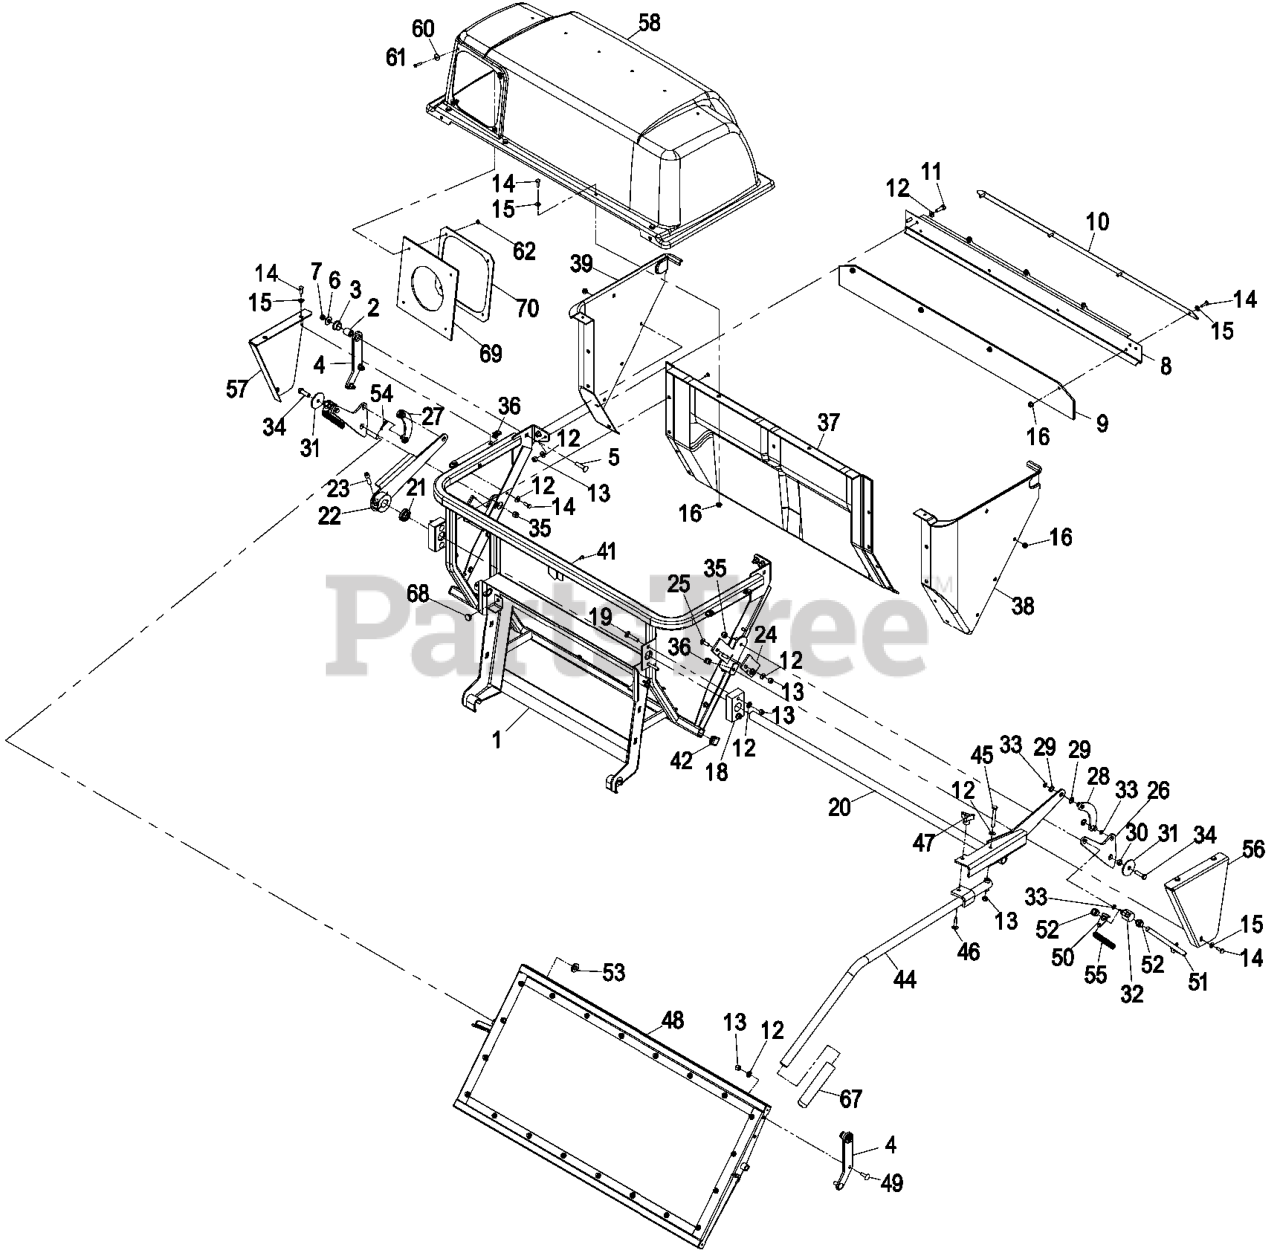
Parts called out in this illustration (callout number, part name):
1	FRAME ASM
2	PIN-PIVOT, HINGE
3	BEARING
4	PLATE-HINGE
5	SCREW-CARR
6	WASHER-FLAT
8	PLATE-REAR
9	SEAL-DOOR
10	STRAP-HOLD DOWN
11	SCREW-HH
12	WASHER-PLAIN
13	NUT-LOCK, NI
14	SCREW-HH
15	WASHER-FLAT
18	BEARING
19	BOLT-CAR
20	BELLCRANK
21	SHAFT-COLLAR
23	SCREW-HSH
24	STOP-LINKAGE
25	BOLT-CARR
26	ARM-LINKAGE, DOOR
27	LINK-RH
28	LINK-LH
29	WASHER-NYLON
30	BEARING-LINKAGE, PIVOT
32	TRUNNION-LINK
33	RING-RETAINING
34	SCREW-HH
35	NUT-LOCK, NI
36	Nut, Retainer-Panel 1/4-20
37	PANEL-BAGGER
38	PANEL-BAGGER, LH
39	PANEL-BAGGER, RH
41	RIVET-BLIND
44	HANDLE-QD7
45	SCREW-HH
46	Bolt-Carriage 5/16-18 X 1 1/4
47	KNOB-3 PRONG
48	Asm, Door
49	SCREW-CARR
50	ANCHOR-SPRING
51	LINK-DOOR
52	NUT-HEX
53	WASHER-FLAT
54	PIN-COTTER
58	ASM, HOOD
60	WASHER-FLAT
61	SCREW-PPH
62	NUT-LOCK, NI
67	HANDLE-GRIP
69	SEAL-CHUTE
70	CLAMP-SEAL
